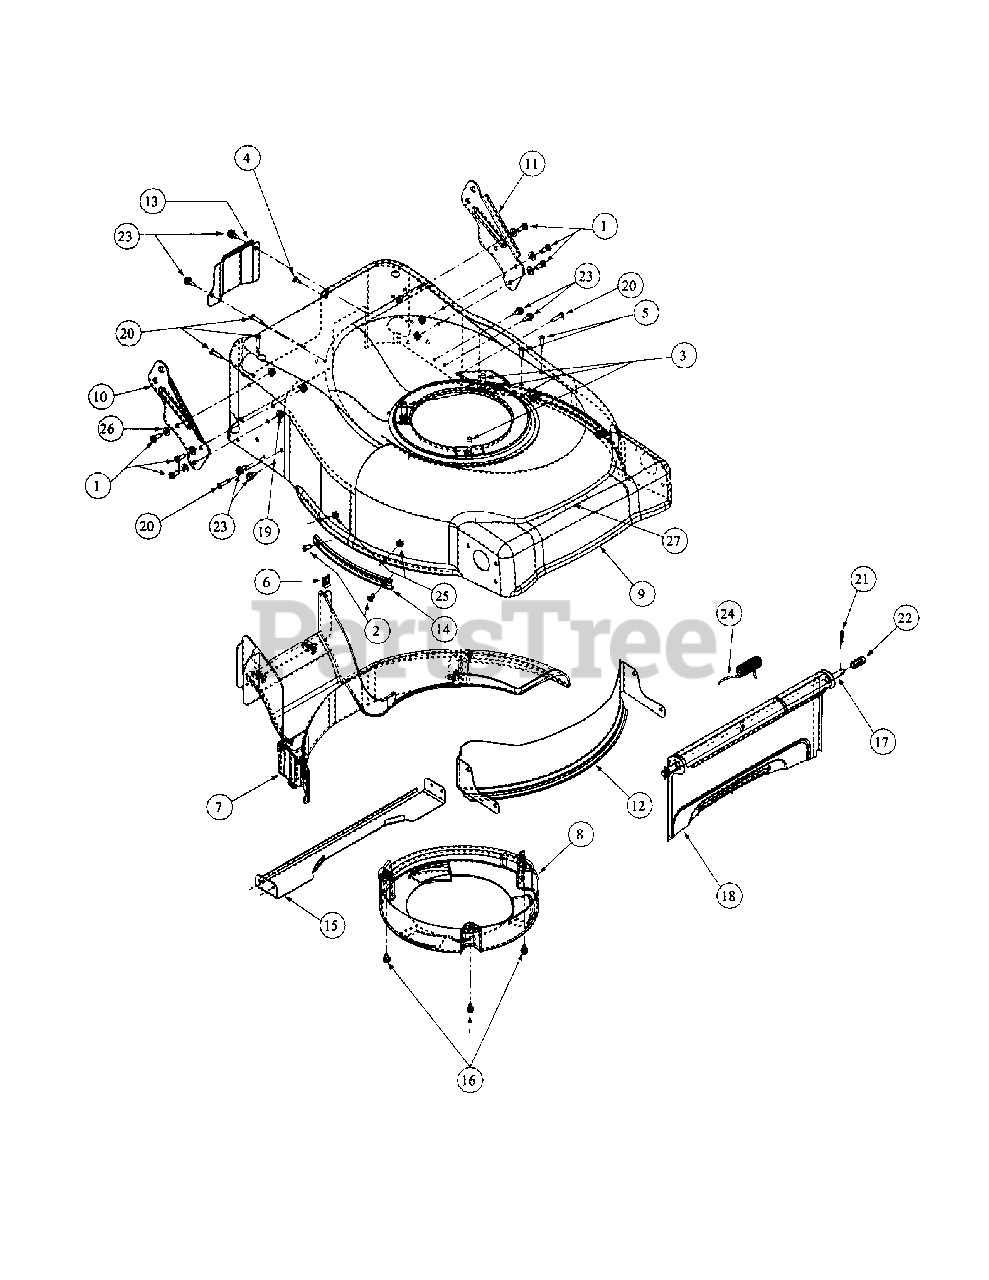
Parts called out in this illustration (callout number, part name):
1	HHCS, 1/4-20, .620, GR5, Standard
2	Screw Button HD, 1/4-20 x .5
3	Screw, TTSems, 3/8-16, 1.250, HXLWS
4	Screw, B, 10-16, 0.500, TRUSTRX1
5	Screw, HL, 12-16:0.750, TRUSTRX1
6	U-Nut, 10-16
7	Baffle, RR, 21" Commercial
8	Cover, 21" Commercial
9	Deck, 21" Commercial
10	Bracket, Handle, RH Commercial
11	Bracket, Handle, LH Commercial
12	Baffle Front Commercial 10.81 R
13	Cover Plate
14	Guard, Deck Side Flange
15	Bracket, Support Baffle
16	Screw, TT, 1/4-20, 0.375, Hex Indicator Washer
17	Rod, Pivot, Chute Door, .375 D1
18	Door, Grassbag, 21" RB
19	Nut, 1/4-20, Hex Flange, Lock Group F
20	Screw, HL, 12-16, 1.000, TRUSTRXI
21	Cotter Pin, INT .072 x 1.12 LG
22	Spacer, .315 x .50 x 1.02 LG
23	Screw, AB, 1/4-14, 0.625, Hex Indicator Washer
24	Spacer, Torsion, LH 0.120 x 15C
25	Hex Nut, 1/4-20 GRC, Lock
26	Flat Washer, 1/4 x .630 x .0515
27	Label, 21" Commercial
